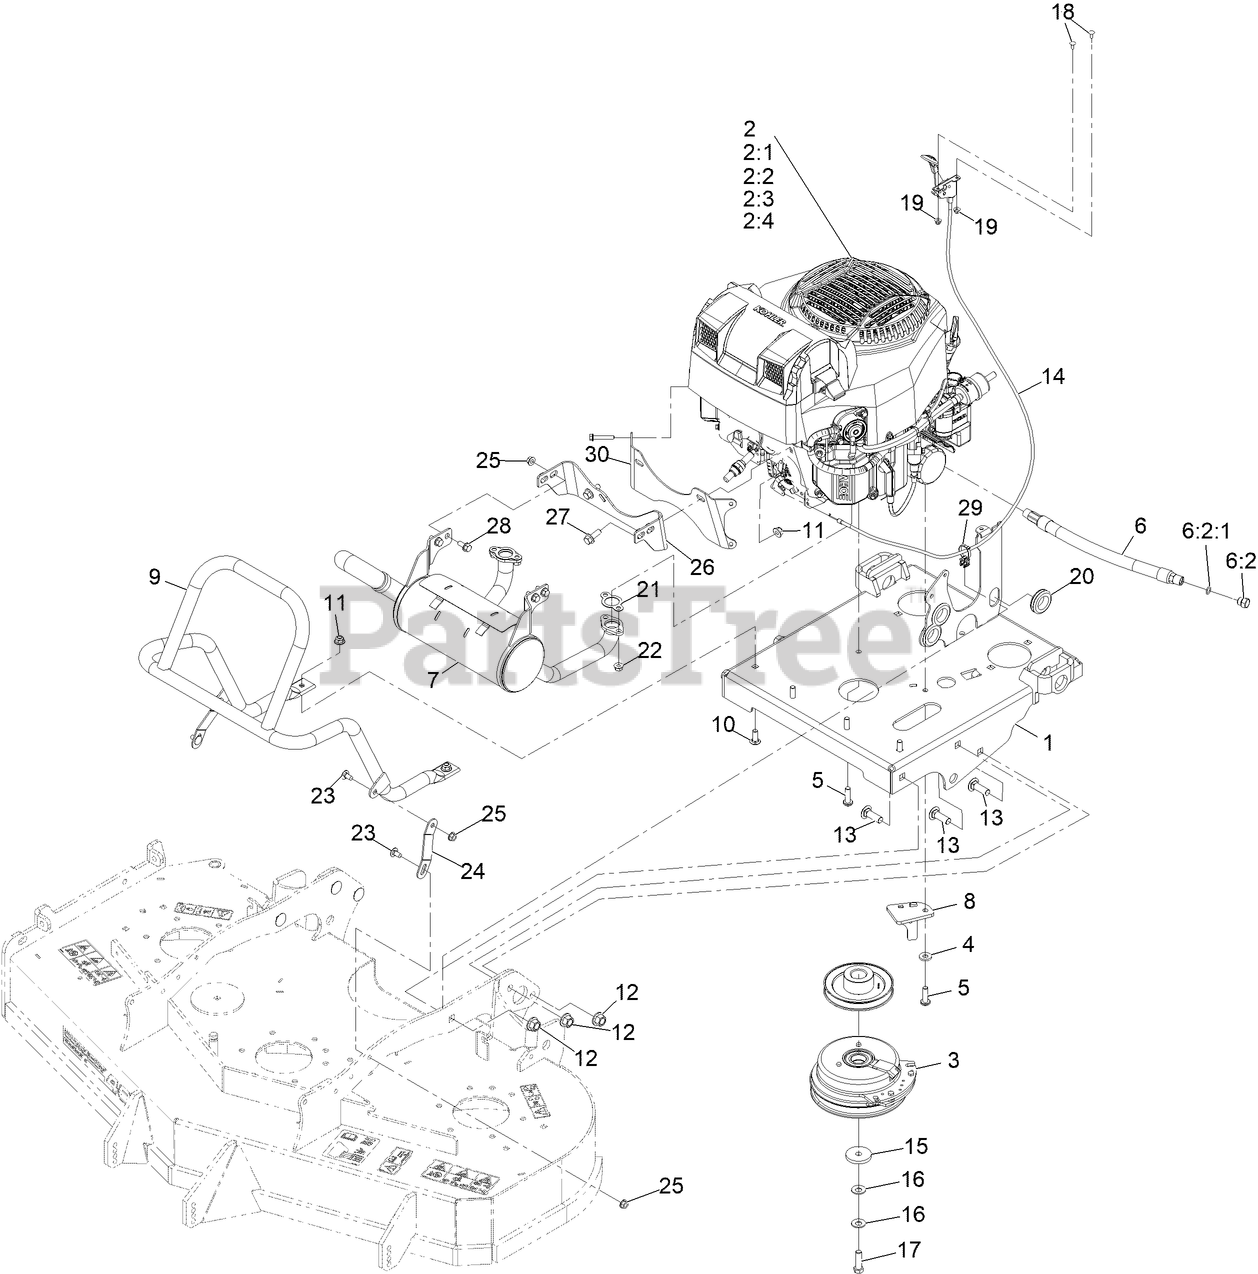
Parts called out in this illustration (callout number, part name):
1	ASM-ENGINE DECK
2:1	Element Pre-Cleaner
2:2	Kohler 16 083 01-S Engine Air Filter
2:3	Filter-Oil
2:4	Kohler 24 050 13-S Fuel Filter
3	Clutch, Cms-175
4	WASHER-BELLEVILLE
5	Screw-PH-T45
6	OIL DRAIN HOSE ASM
6:2	PLUG-HH
6:2:1	O-RING
7	MUFFLER- KOHLER EFI
8	ASM-CLUTCH ANCHOR
9	Tube-Guard Muffler
10	SCREW-CARR
11	NUT-HF, NI
12	Nut-Lock 1/2-13
13	Screw-CARR
14	CONTROL,THROTTLE
15	WASHER-CLUTCH
16	WASHER-SPRING
17	SCREW-HH 7/16-20 X 1 1/2 W/LOCTITE
18	BOLT-CARR
20	GROMMET
21	GASKET-EXHAUST
22	NUT-FLANGE
23	SCREW-CARR
24	Strap, Muffler Guard
26	BRACKET-MUFFLER
27	SCREW-HHF 3/8-16 X 1
28	SCREW-HHF
29	Clip-Edge W/Tie, Perpendicular
30	Bracket-Muffler
